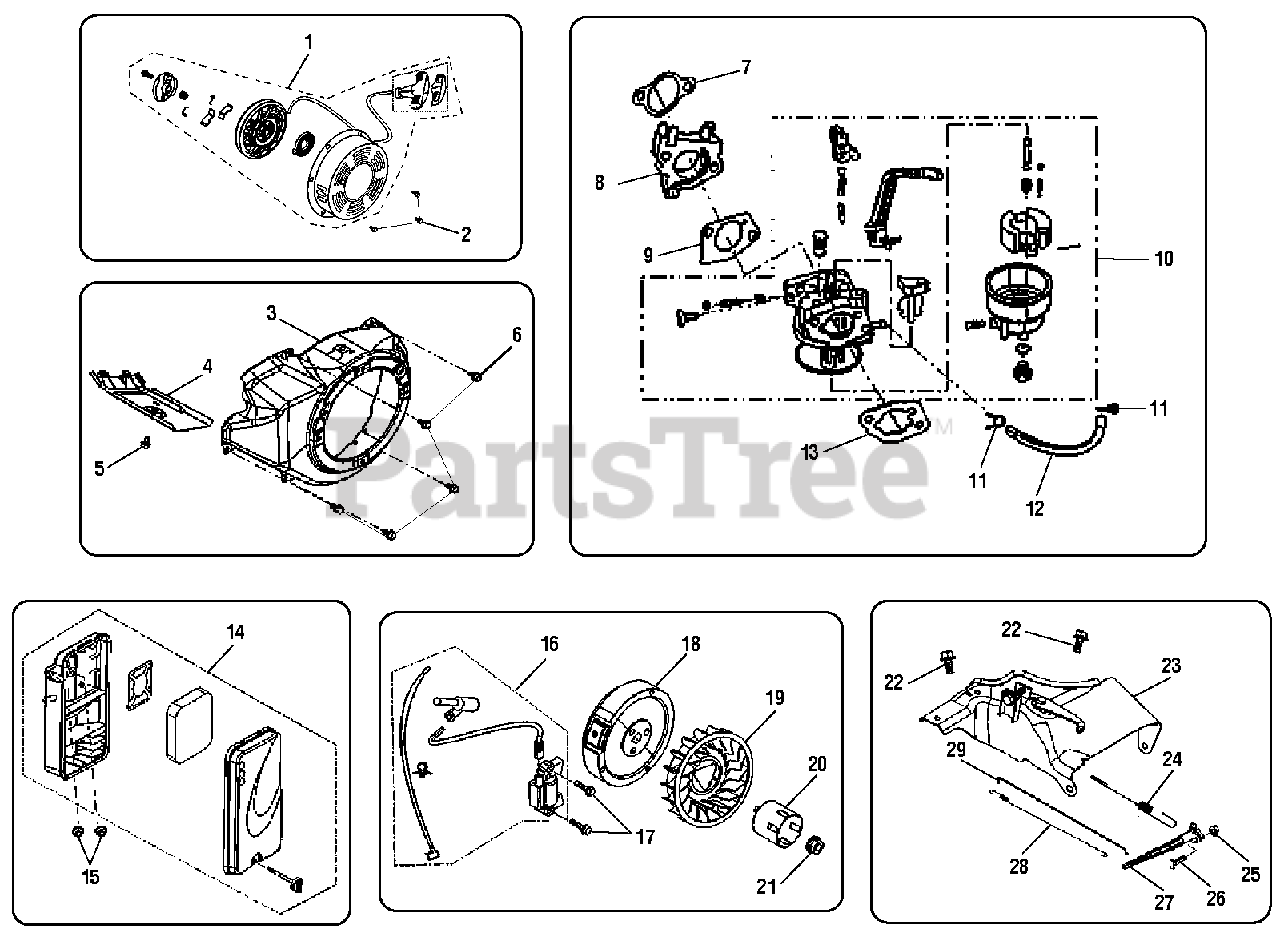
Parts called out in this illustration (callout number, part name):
1	Recoil Starter Assembly
4	Cylinder Body Shroud
7	Inlet Gasket
8	Carburetor Insulator Plate
9	Carburetor Gasket
10	Carburetor Assembly
13	Air Cleaner Gasket
14	Air Cleaner Assembly
16	Ignition Coil
18	Flywheel Assembly
20	Starter Pulley
21	Flywheel Nut
23	Throttle Control Assemby
24	Governor Spring
26	Bolt
27	Governor Support Assembly
28	Throttle Valve Return Spring
29	Governor Rod
